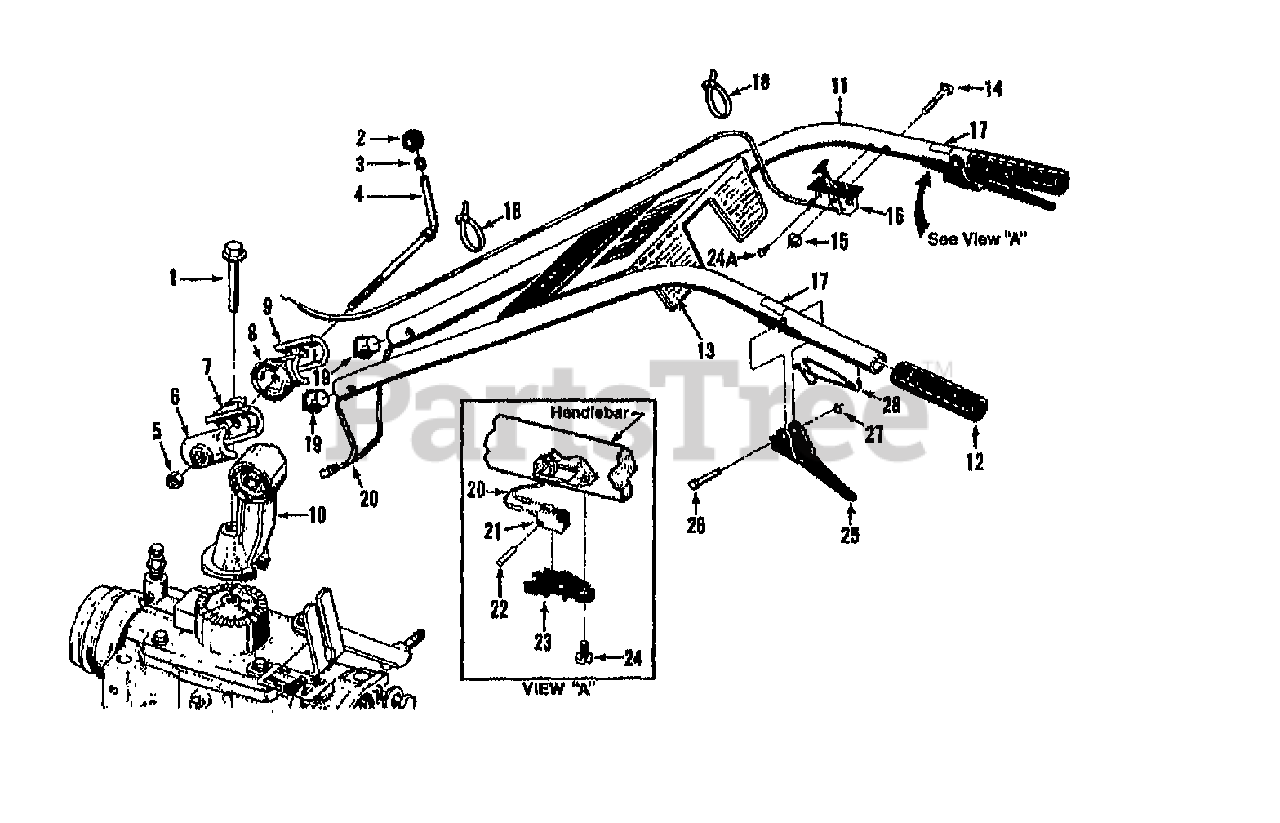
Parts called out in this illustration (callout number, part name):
1	BOLT 1/2-13X3.5 FH GR5
2	KNOB-CONTROL (INCL. 3)
3	RING-TOLERANCE .5325 ID
4	STUD-H/BAR W/NUT & RING (INCL. 2,3 & 5)
5	NUT-HEX JAM 1/2-13
6	CLAMP-LH HORSE 1021-1
7	RATCHET-H/BAR RED 2542-1
8	RATCHET-RH RED HORSE 2542-2
9	CLAMP-RH HORSE 1021-2
10	BASE-H/BAR RED 2534A
11	ASSM-HANDLEBAR W/GRIPS (INCL. 2 OF EA. 12, 17 & 28 AND ONE 13)
12	GRIP-H/BAR SMOOTH
13	DECAL-CONTROL PANEL HORSE
13	DECAL-CONTROL PANEL (11HP)
14	BOLT-CH 1/4-20X2.00 ZP
15	NUT-HF/LK 1/4-20 ZP
16	CABLE-THROTTLE 7 I/C B&S {12068/069/080/081/087}
16	CABLE-THROTTLE 7&8 B&S {12074/075/088/089/090}
16	CABLE-THROTTLE 8HP OPC {12070/071/082/083}
17	DECAL-FWD INTERLOCK
18	TIE-RED
19	RETAINER-HARNESS H/B OPC
20	HARNESS-WIRE OPC HORSE
21	SWITCH-H/B OPC
22	PIN-LK .11X.58 HORSE OPC
23	HOUSING-SWITCH OPC
24	SCR-HW M10-24X.5 STH ZP
24A	SCR-PHS M10-32X.5 STH ZP
25	LEVER-HORSE OPC
26	PIN-PIVOT OPC LEVER
27	RING-KLIP 5304-25
28	SPRING-H/B LEVER
